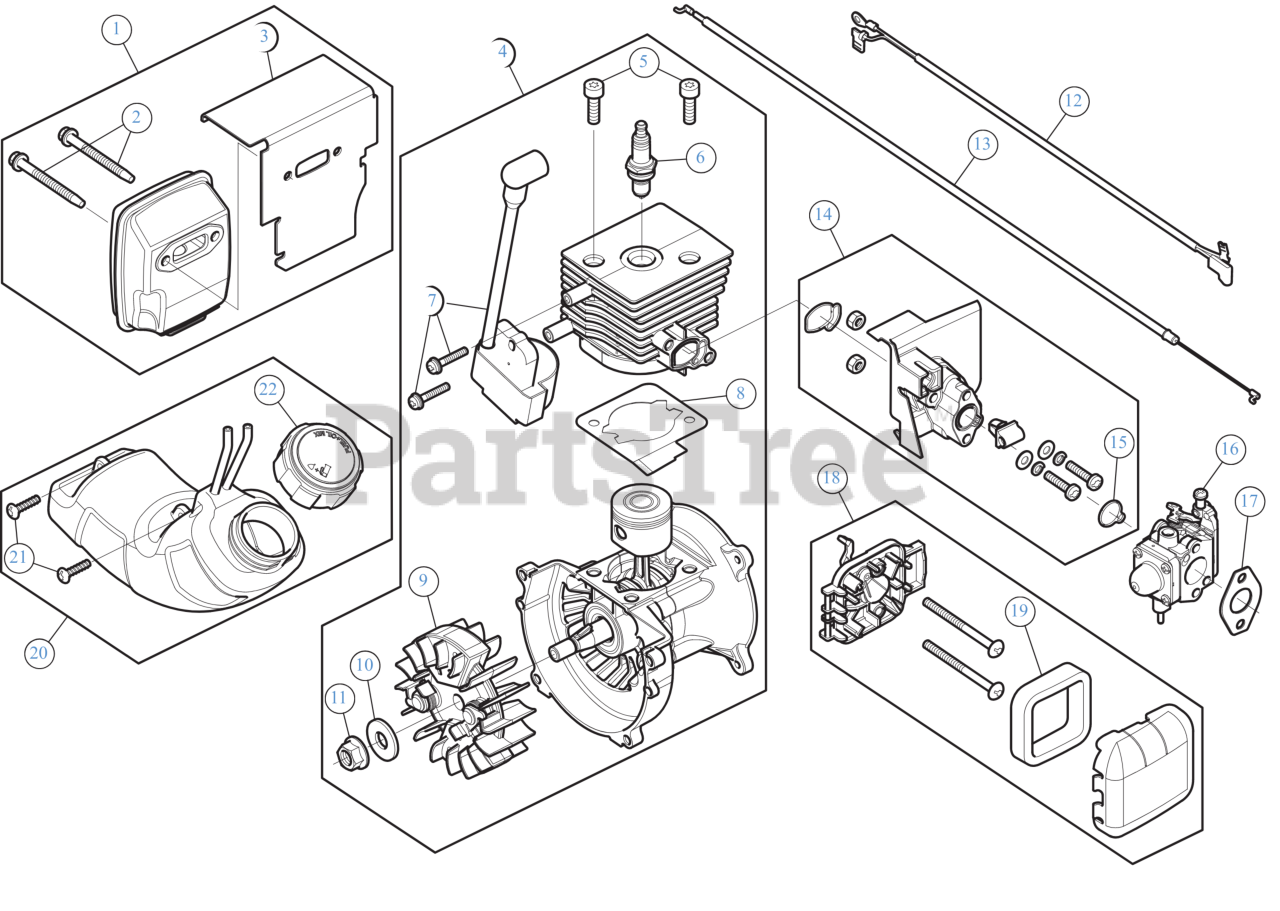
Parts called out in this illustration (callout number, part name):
1	MUFFLER ASSEMBLY 27CC
2	MUFFLER SCREW
3	MUFFLER GASKET
4	SHORT BLOCK
5	SCREW 1/4 x 20 x .8125
6	SPARK PLUG
7	MODULE
8	GASKET CYL
9	FLYWHEEL ASSEMBLY
10	WASHER .406X1.0X.095
11	NUT 3/8-24
12	LEAD WIRE
13	THROTTLE CABLE
14	INTAKE ASSEMBLY
15	O-RING
16	CARBURETOR ASSEMBLY
17	GASKET CARB
18	AIR CLEANER ASSEMBLY
19	AIR FILTER
20	FUEL TANK ASSEMBLY
21	SCREW 8-16 x 3/4
22	FUEL CAP
